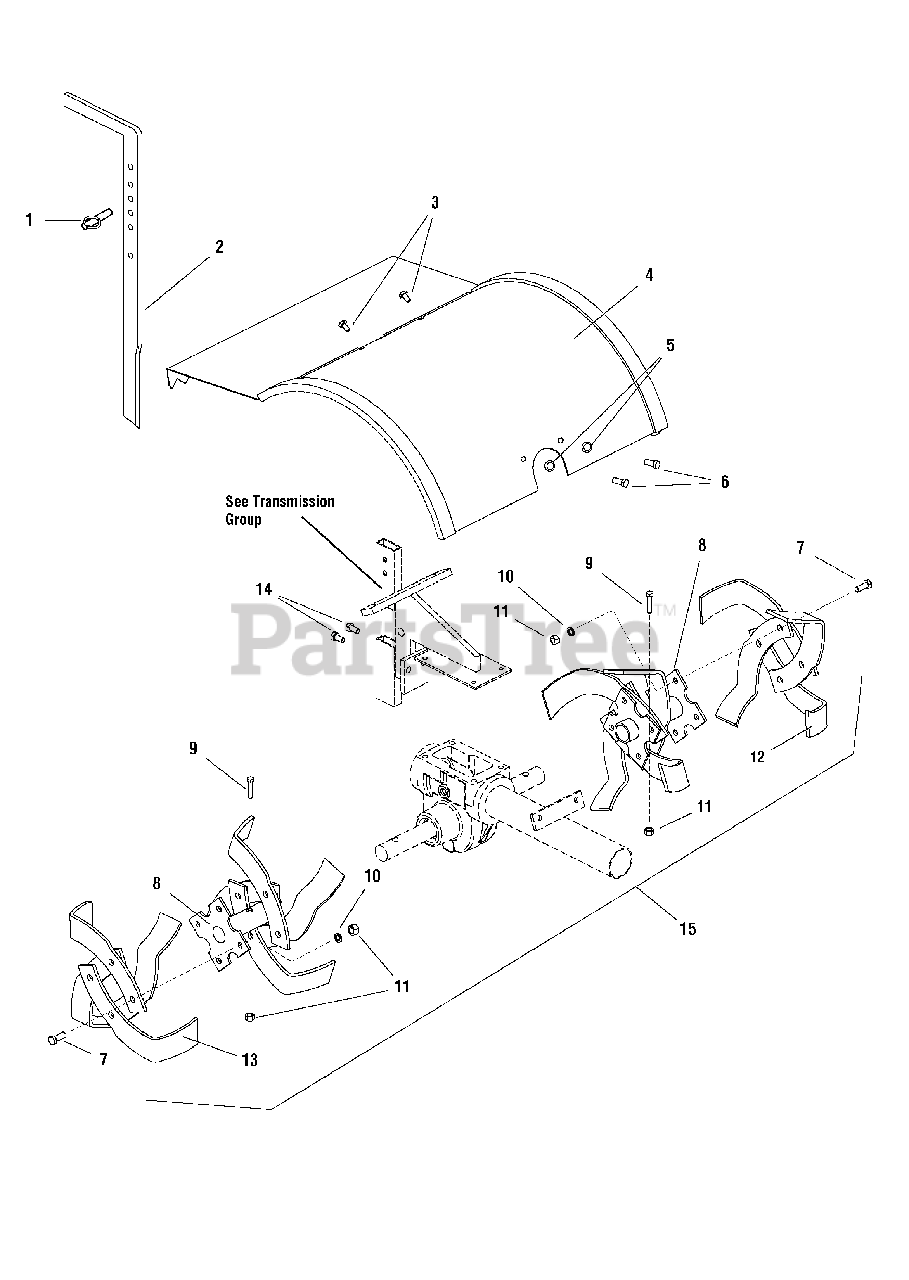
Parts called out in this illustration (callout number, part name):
1	PIN, DETENT 5/16
2	LEVER, Depth Regulator
3	CAPSCREW, Hex Head, 1/4-20 x 1/2
4	HOOD, Tiller, No Decal
5	LOCKWASHER, 5/16
6	CAPSCREW, Hex Head, 5/16-18 x 1/2
7	CAPSCREW, Hex Head, 3/8-16 x 1
8	HOLDER, Tine Blade Left and Right
9	CAPSCREW, Hex Head, 3/8-16 x 1-3/4
10	LOCKWASHER, 3/8
11	NUT, Hex Centerlock, 3/8-16
12	TINE BLADE, Left Side
13	TINE BLADE, Right Side
14	BOLT, Hex Flange Head, 5/16-18 x 1/2
15	REPLACEMENT KIT, Tine Blade Holder & Tines
